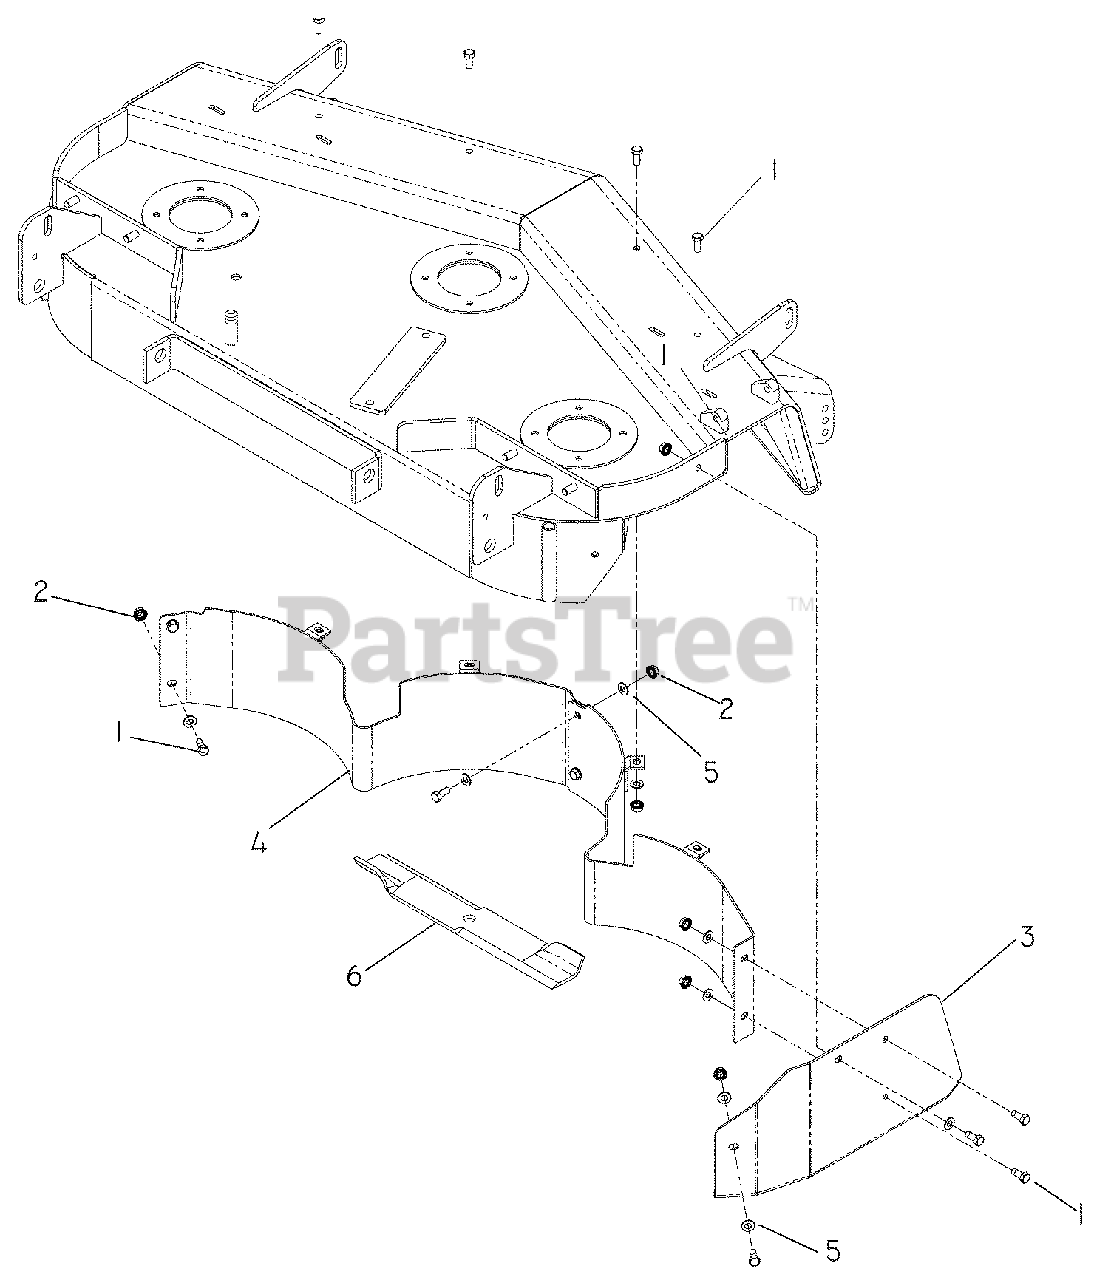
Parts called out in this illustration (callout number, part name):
1	HCS, 5/16 -18 X ¾
2	NUT 5/16 -18, WHIZ
3	BAFFLE, RT, 52" DECK
4	BAFFLE, LT, 52" DECK
5	WASHER, 5/16, SAE
6	BLADE 52" DECK
7	52" MULCH CAP
